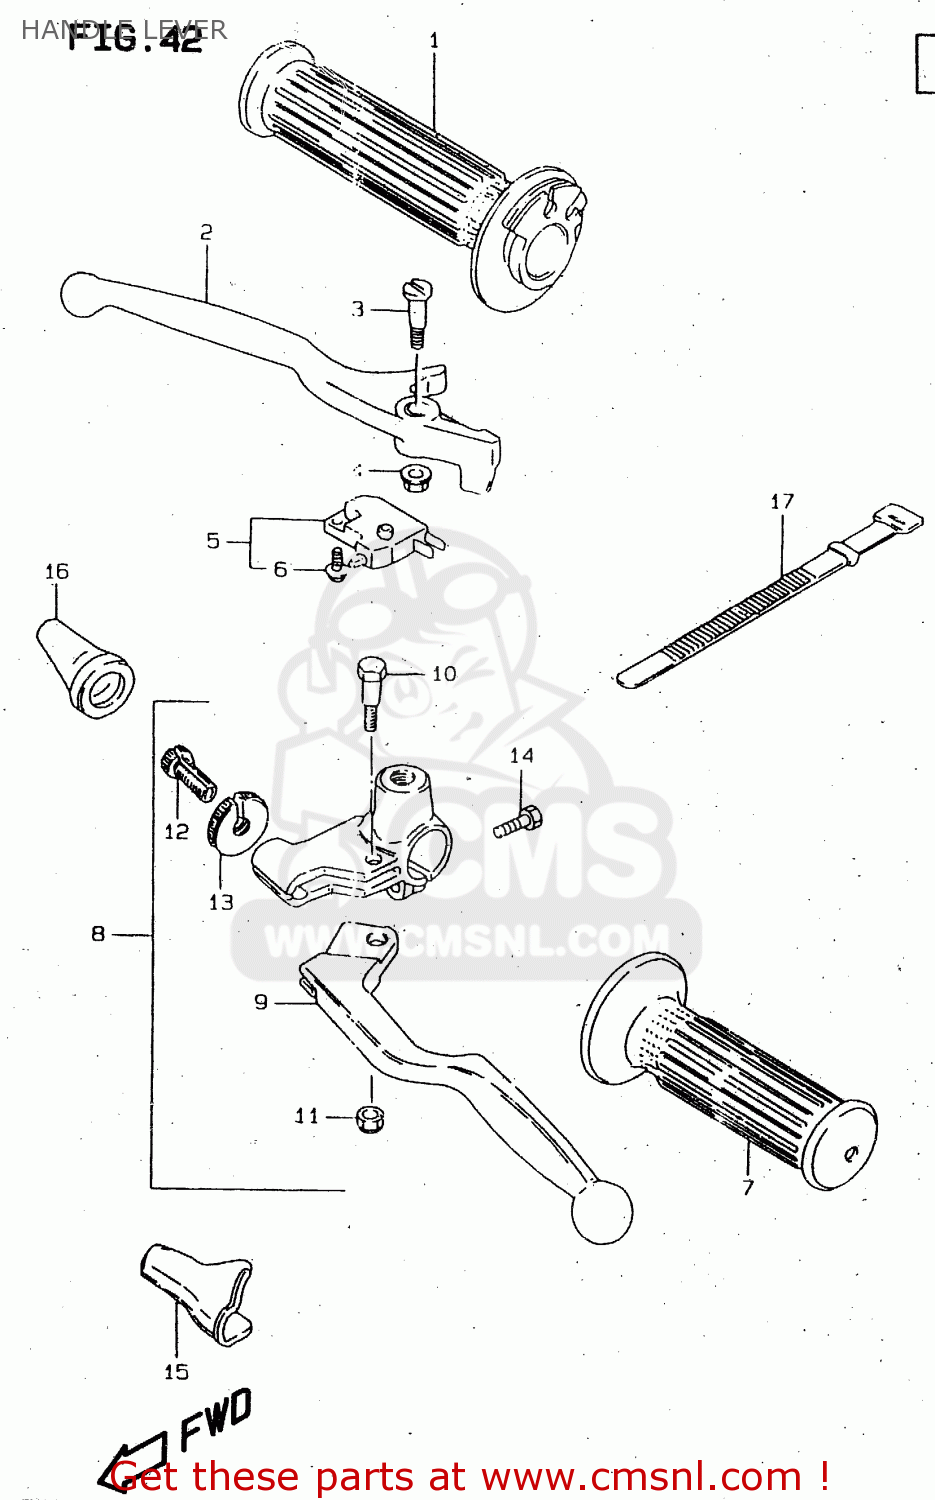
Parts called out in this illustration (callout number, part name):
1	GRIP,THROTTLE
2	LEVER,BRAKE
3	BOLT,LEVER PIVOT
4	NUT
5	SWITCH ASSEMBLY,STOP
6	SCREW
7	GRIP,L
8	LEVER ASSY,CLUTCH
9	LEVER,CLUTCH
10	BOLT,LEVER PIVOT
11	NUT 6MM
12	ADJUSTER,CABLE
13	NUT,CABLE ADJUSTER
14	BOLT,CLUTCH LEVER HOLDER
15	COVER,CLUTCH LEVER
16	BOOT,CLUTCH CABLE
17	CLAMP(L:120)
